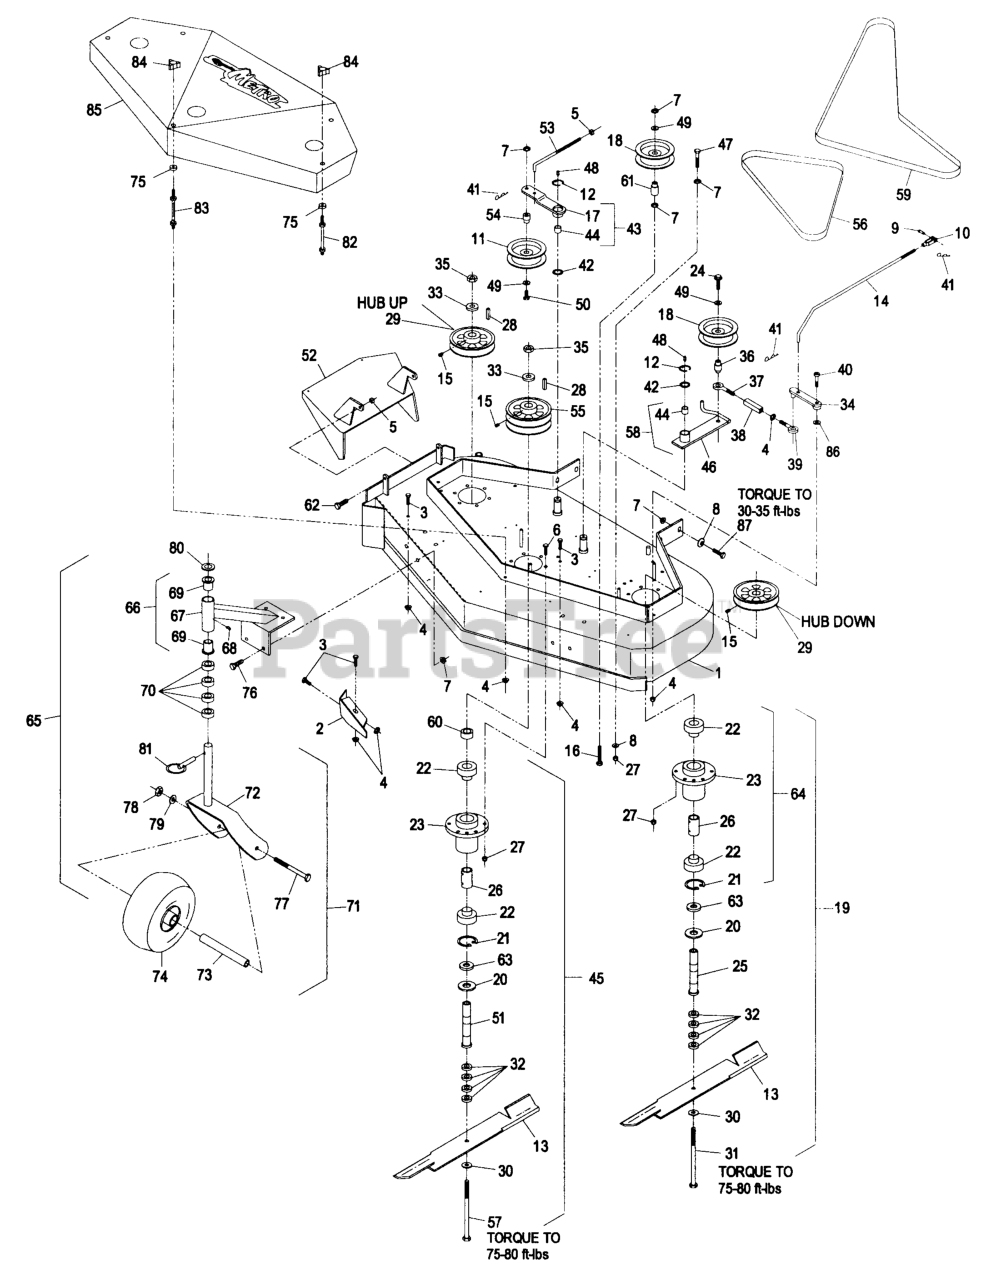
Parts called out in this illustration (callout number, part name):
2	BAFFLE-DOGLEG
9	PIN-CLEVIS
10	YOKE-ADJUSTABLE
11	IDLER,PULLEY
14	ARM-ASSIST, LINKAGE
15	SCREW-SET
16	BOLT,TAP HH3/8-16X2-1/4
17	Arm Weldmt, Rh
19	HOUSING,CUTTER COMPLETE(S
20	GUARD-BEARING, BOTTOM
22	BEARING
25	TUBE-SPINDLE, SHORT
26	SPACER-BEARING
30	WASHER-SPRING
31	SCREW-CAP, HH
33	WASHER-RETAINER, SHEAVE
36	BUSHING-ENGAGEMENT
37	EYEBOLT-THREAD, LH
38	BODY-TURNBUCKLE
39	EYEBOLT-THREAD, RH
40	BOLT,SHLDR KSKH 3/8 X 1
41	PIN-COTTER
42	WASHER-SPINDLE
43	ARM WLDMNT W/BUSHING
44	BEARING,POWDERED METAL
45	HOUSING,CUTTER COMPLETE(S
51	TUBE,SPINDLE LONG
53	LINKAGE
54	BUSHING-IDLER
56	BELT,FRONT DECK
57	SCRW,CAP HH 5/8-18X8.5
59	BELT,BLADE DRIVE
60	SPACER,SHEAVE/BEARING
61	BUSHING,IDLER
63	SPACER-PULLEY/BEARING
65	CASTER/MOUNT ASM
66	SUPPORT ASM
69	BEARING-FLANGED
70	SPACER-CASTER
80	WASHER-FLAT
82	STUD-SHIELD, BELT (SHORT)
83	STUD-SHIELD, BELT (LONG)
84	KNOB-3 PRONG
